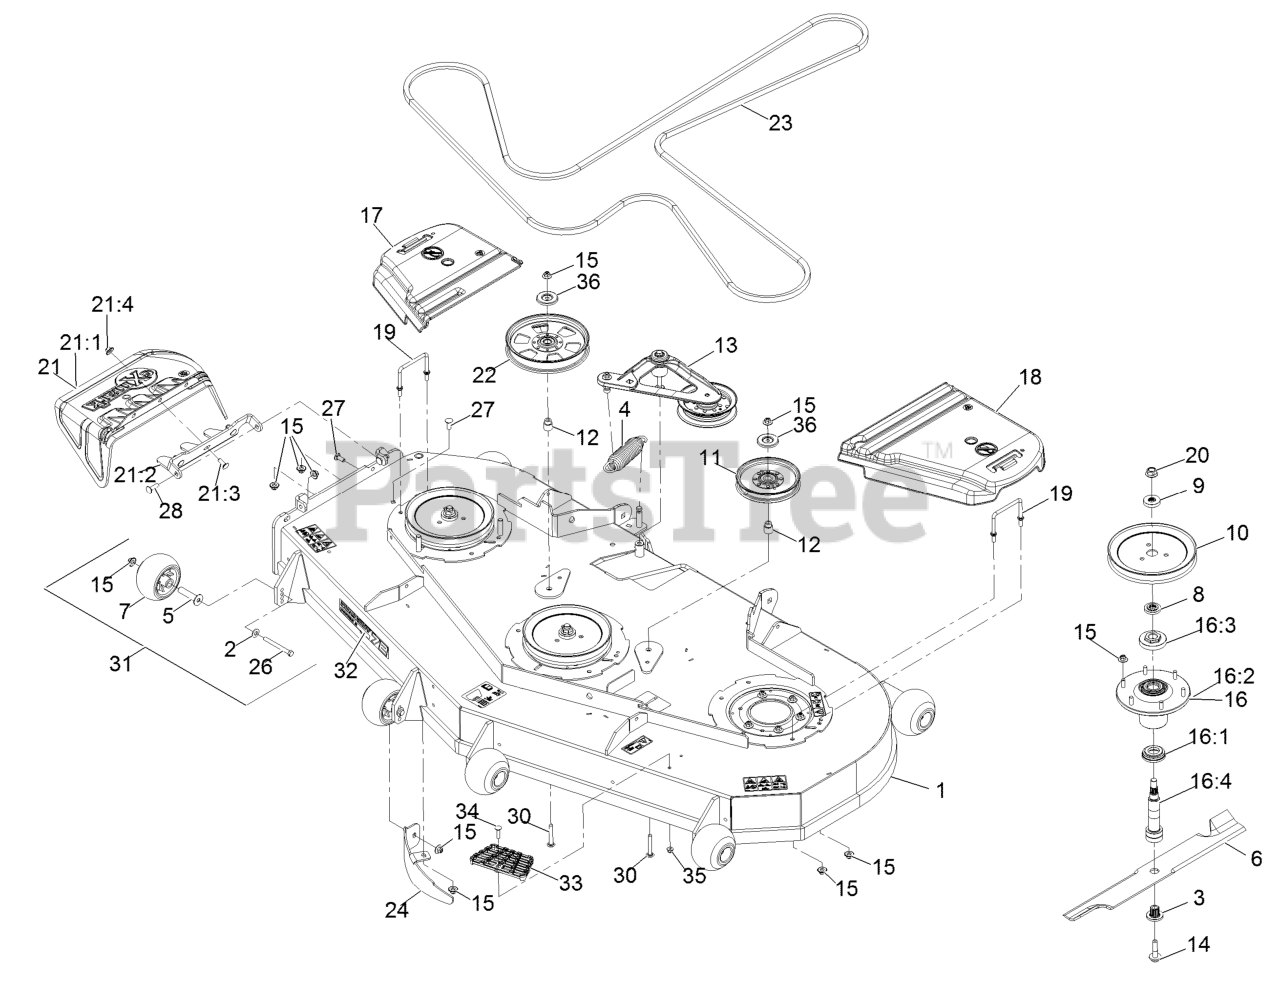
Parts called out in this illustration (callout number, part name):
1	ASM,DECK W/DECALS 724
2	WASHER-BELLEVILLE
3	BUSHING,SPLINED
4	SPRING-EXTENSION
5	AXLE, ROLLER
7	ROLLER-SCALP, ANTI
8	SPACER,SPLINED STEPPED
9	SPACER,SPLINED
10	SHEAVE,BLADE DRIVE 9.00
11	IDLER-PULLEY
12	BUSHING-IDLER
13	DECK IDLER ASM
14	SCREW,SEMS 1/2-20 X 2.19
15	Nut-Nyloc 3/8-16 Flg
16	ASM,SPINDLE HOUSING
16:1	GUARD,BOTTOM
16:2	ASM,CUTTER HOUSING
16:3	NUT, SPINDLE 7/8-14
16:4	SPINDLE,DOUBLE SPLINE
17	COVER-BELT, RH
18	COVER-BELT, LH
19	WIREFORM-COVER
20	NUT-FLANGE, CENTERLOCK
21	ASM,DISCHARGE CHUTE
21:1	CHUTE,DISCHARGE
21:2	BRACKET,DISCHARGE CHUTE
21:3	SCREW-CARR
21:4	Nut-Nyloc 3/8-16 Flg
22	PULLEY-IDLER, FLAT
23	BELT-V
24	BAFFLE-DOGLEG, LZ72
26	SCREW-HH 3/8-16 X 3 3/4 GR 8
27	SCREW-CARR
28	Bolt-Carriage 3/8-16 X 1 1/4
30	SCREW-CARR
31	KIT, ANTI-SCALP ROLLER
32	DECAL, 726
33	STEP-DECK
34	Bolt-Carriage 5/16-18 X 1 1/4
35	NUT-HF, NI
36	SHIELD-DUST
